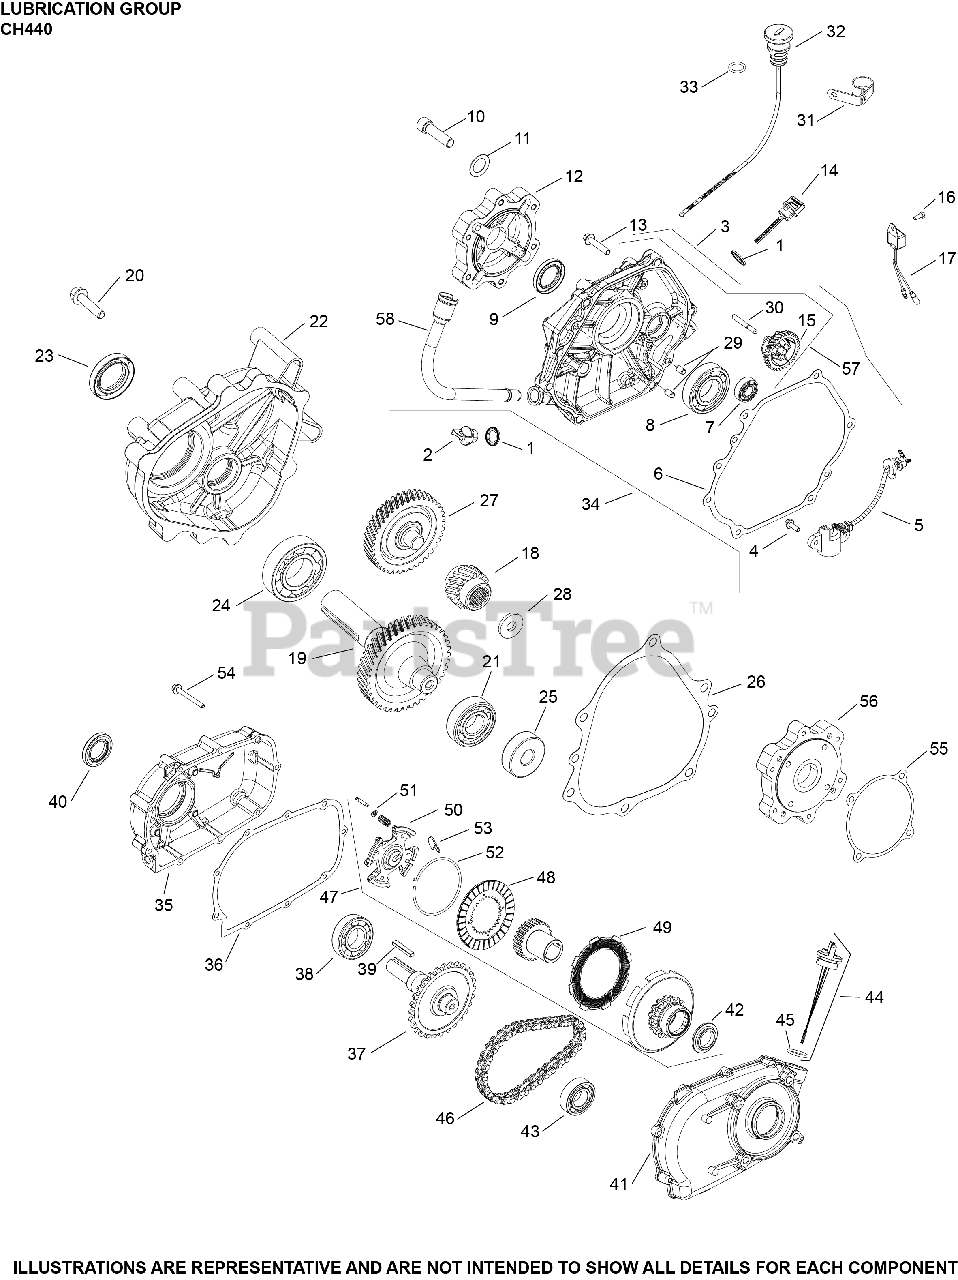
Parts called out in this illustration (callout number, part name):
1	SEAL, OIL
4	SCREW, M6 X18
5	SWITCH, OIL SENSOR ASSEMBLY
8	BEARING, BALL
13	SCREW, CLOSURE PLATE (CKY)
14	DIPSTICK ASSEMBLY
14	DIPSTICK - USE 17 038 08-S
15	GOVERNOR ASSEMBLY
16	SCREW, HEX/PHILLIPS M5
17	CONTROL, OIL ALERT UNIT
30	SHAFT, GOVERNOR GEAR
34	CLOSURE & BEARING PLATE
